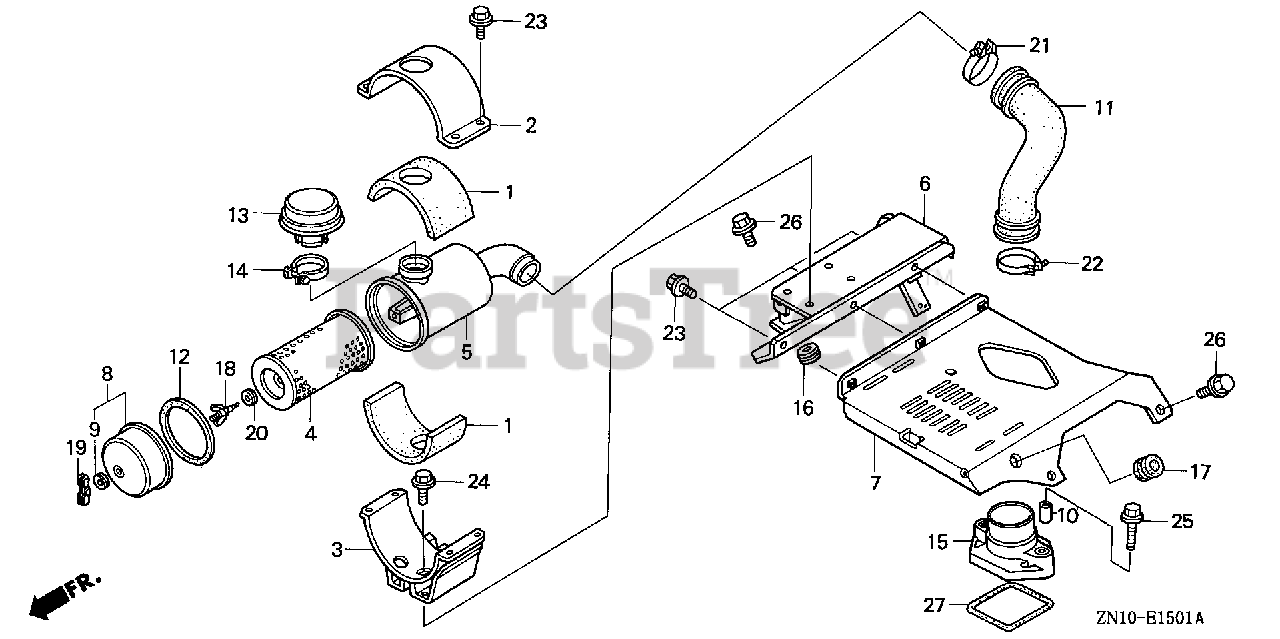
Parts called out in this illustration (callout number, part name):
1	RUBBER, AIR CLEANER HOLDER (UPPER)
2	HOLDER, AIR CLEANER (UPPER)
3	HOLDER, AIR CLEANER (LOWER)
4	ELEMENT, AIR CLEANER
5	HOUSING, AIR CLEANER (SNORKEL)
6	STAY A, AIR CLEANER (SNORKEL)
7	STAY B, AIR CLEANER (SNORKEL)
8	COVER, AIR CLEANER
9	GROMMET, AIR CLEANER
10	COLLAR A, AIR CLEANER
11	TUBE, AIR CLEANER CONNECTING
12	SEAL, AIR CLEANER
14	CLAMP ASSY.
15	JOINT B, CONNECTING TUBE
16	GROMMET, RESERVE TANK
18	BOLT, AIR CLEANER
19	WINGNUT (6MM) (BLACK)
20	WASHER, AIR CLEANER
21	BAND, AIR CLEANER CONNECTING TUBE (50)
21	BAND, AIR CLEANER CONNECTING TUBE (52)
22	BAND, AIR CLEANER CONNECTING TUBE (58)
23	BOLT, FLANGE (6X12)
24	BOLT, FLANGE (6X16)
25	BOLT, FLANGE (6X28)
26	BOLT, FLANGE (8X20)
27	SEAL, AIR CLEANER HOUSING
